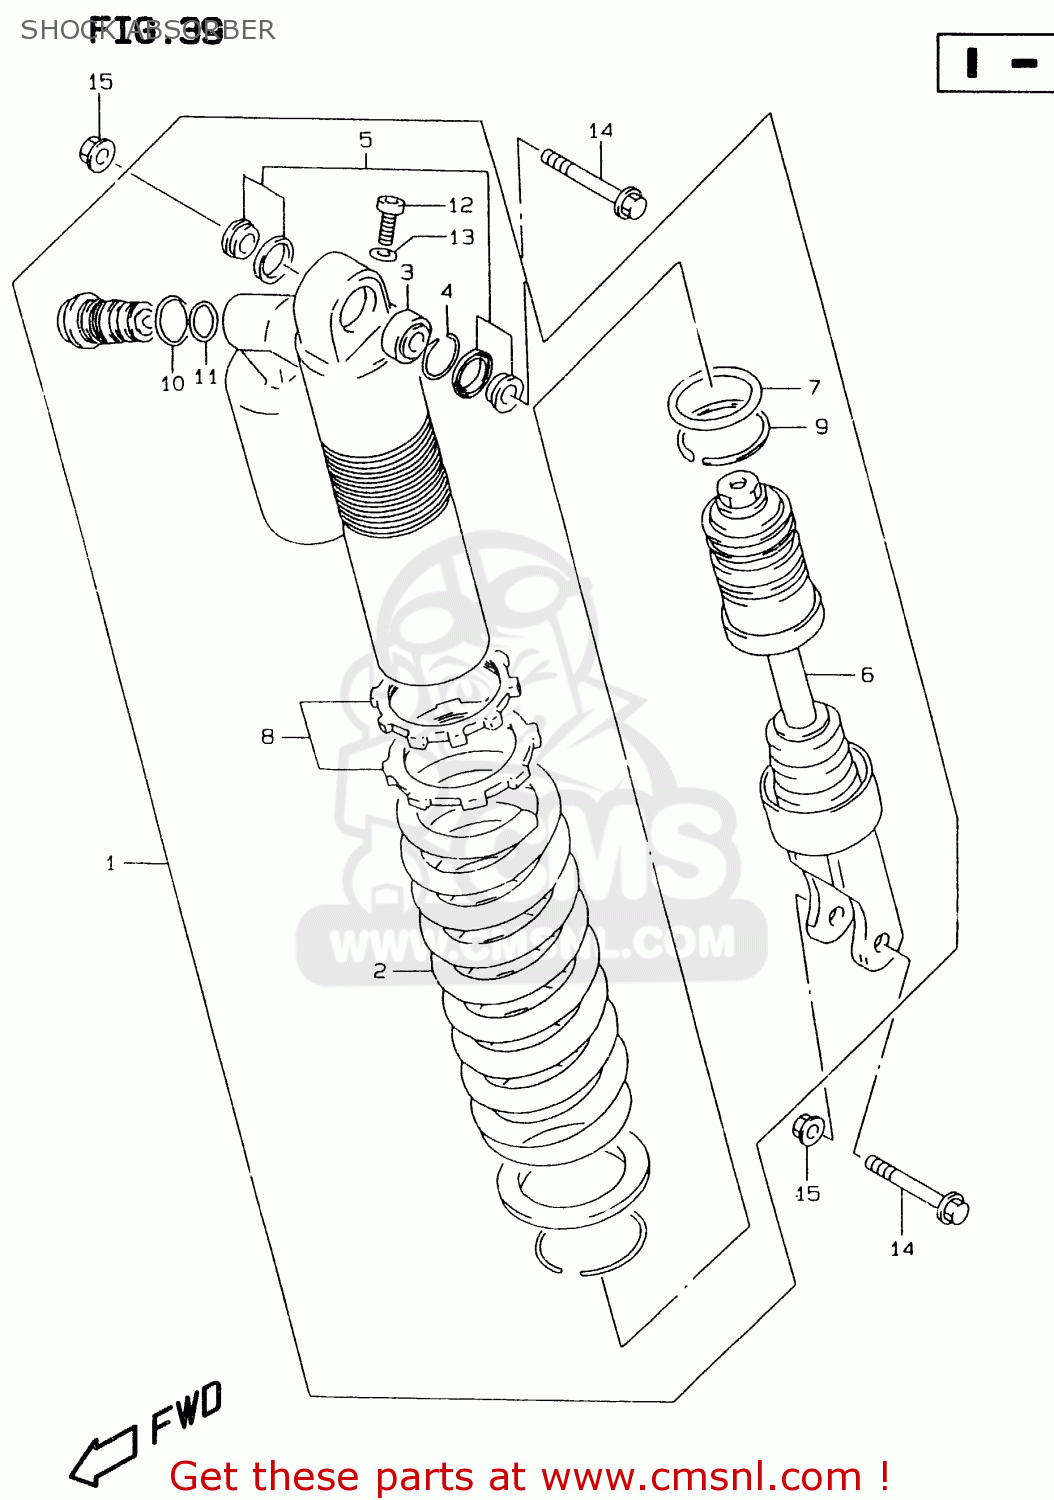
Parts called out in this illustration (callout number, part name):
1	ABSORBER ASSEMBLY,REAR SHOCK
2	SPRING
3	BEARING,RR CUSHION LEVER RR
4	RING,STOPPER
5	COLLAR SET,RR SHOCK ABSORBER
6	ROD,PISTON
7	O RING
8	ADJUSTER SET,SHOCK ABSORBER
9	RING,STOPPER
10	O RING
11	O-RING,FORK BOLT,LOWER
12	BOLT
13	GASKET,DRAIN,PLUG (NAS)
14	BOLT,RR SHOCK ABSORBER
15	NUT
